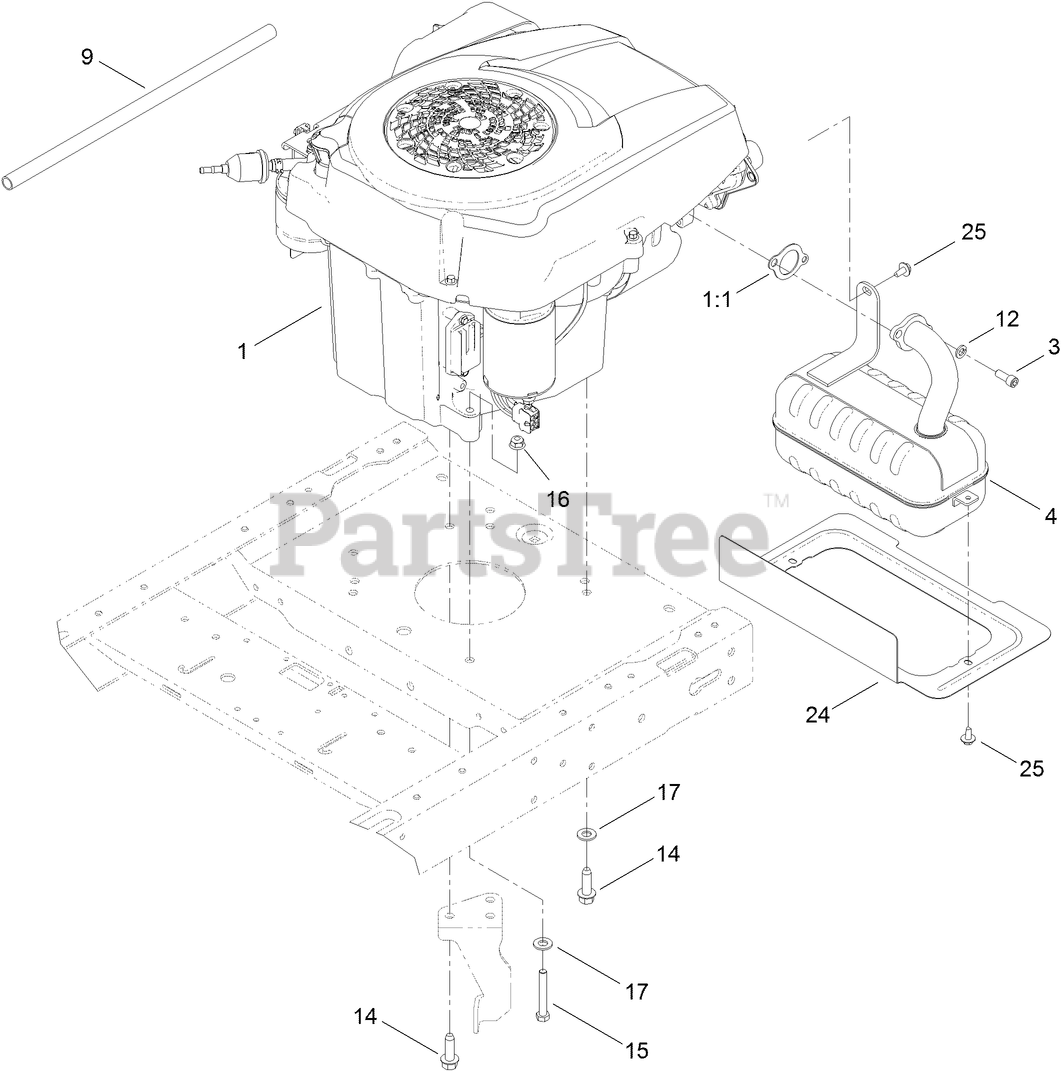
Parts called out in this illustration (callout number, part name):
1	Loose Parts Package
1:1	GASKET-EXHAUST
3	SCREW-HSH
4	MUFFLER-KOHLER
9	TUBE-DRAIN, OIL
12	WASHER-LOCK
14	SCREW-THD
15	SCREW-HH
16	NUT-HF, NI
17	WASHER-FLAT
24	SHIELD-HEAT
25	SCREW-HHFTF
